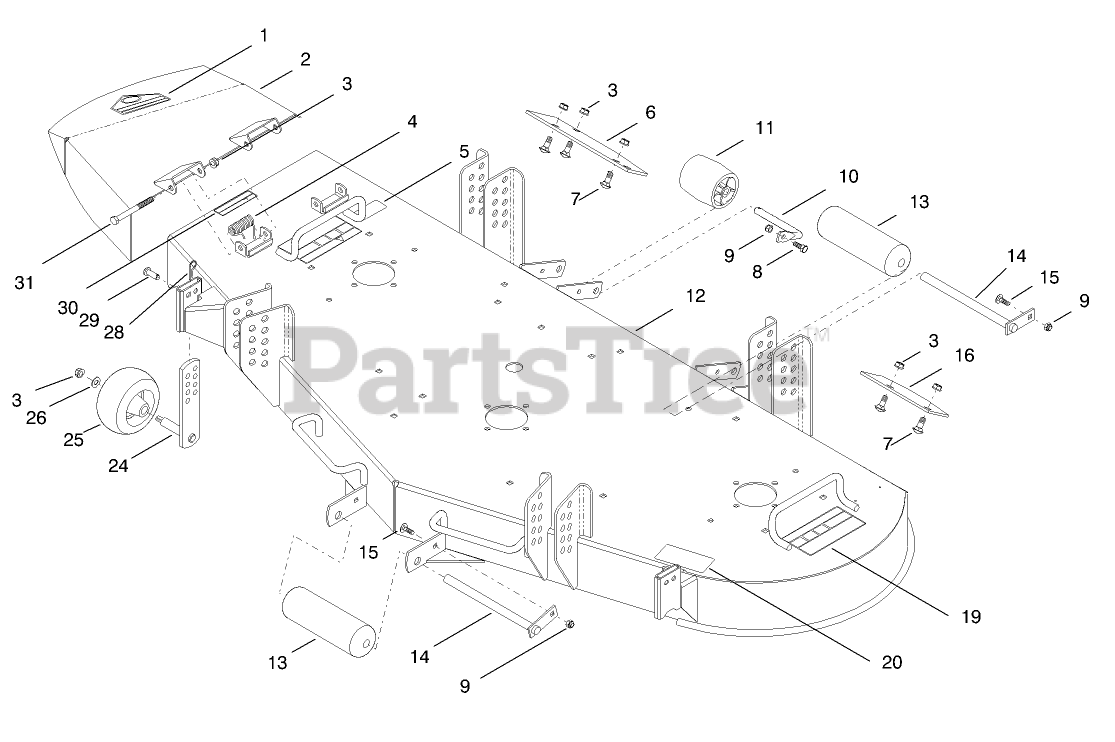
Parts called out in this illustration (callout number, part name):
1	DECAL-DANGER
2	Chute-ASM
2	CHUTE ASM
3	NUT-LOCK, NI
4	SPRING
5	Decal-Safety
6	PLATE-WEAR, RH
7	BOLT-CARR
8	SCREW-HH
9	NUT-LOCK, NI
10	ROLLER-SHAFT
11	Roller
12	DECK ASM
13	ROLLER-ANTI SCALP
14	ROLLER-SHAFT
15	BOLT-CARR
16	PLATE-WEAR, LH
19	DECAL-DANGER, THROWN OBJECT
20	DECAL - WHEEL ADJUSTMENT
24	GAGE-WHEEL
25	WHEEL-GAGE
26	WASHER-FLAT
28	PIN-HAIR
29	PIN-CLEVIS
30	DECAL-DANGER
31	SCREW-HH
